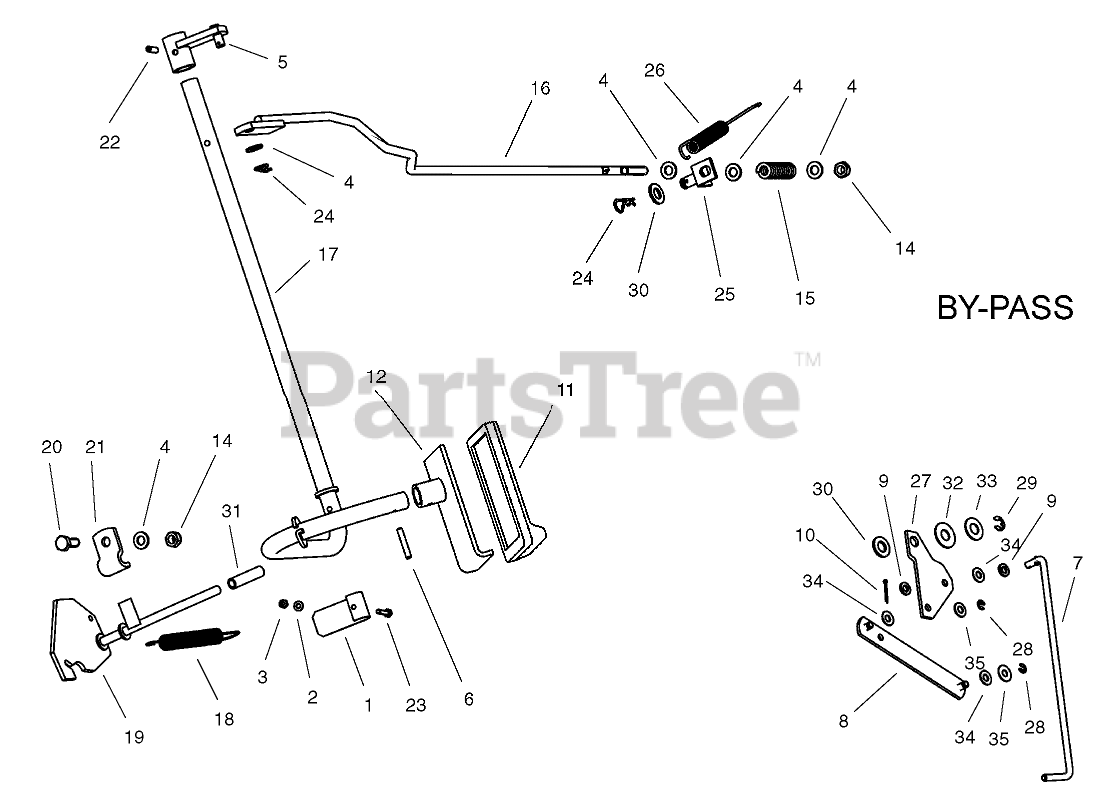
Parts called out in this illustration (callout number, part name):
1	LEVER-SPRING
2	WASHER
3	NUT-HEX
4	WASHER-PLAIN
5	BRACKET-ROD, BRAKE
6	PIN-SPRING
7	ROD-LEVER, BYPASS
8	Lever-Bypass
9	WASHER
10	PIN-COTTER
11	PAD-PEDAL
14	NUT-LOCK, NI
15	SPRING-BRAKE
16	ROD-CONNECTING, BRAKE
17	SHAFT-BRAKE
18	SPRING-BRAKE, HAND
19	LEVER-BRAKE, HAND
20	SCREW-HH
21	CLAMP-LEVER, PARKING BRAKE
22	PIN-SPRING
23	SCREW-HEX
24	PIN-COTTER
25	BRACKET-ROD, BRAKE
26	SPRING
27	Plate-Bypass
28	STIRRUP
29	E-CLIP
30	WASHER-FLAT
32	Washer
33	Washer
34	Washer
35	Washer
